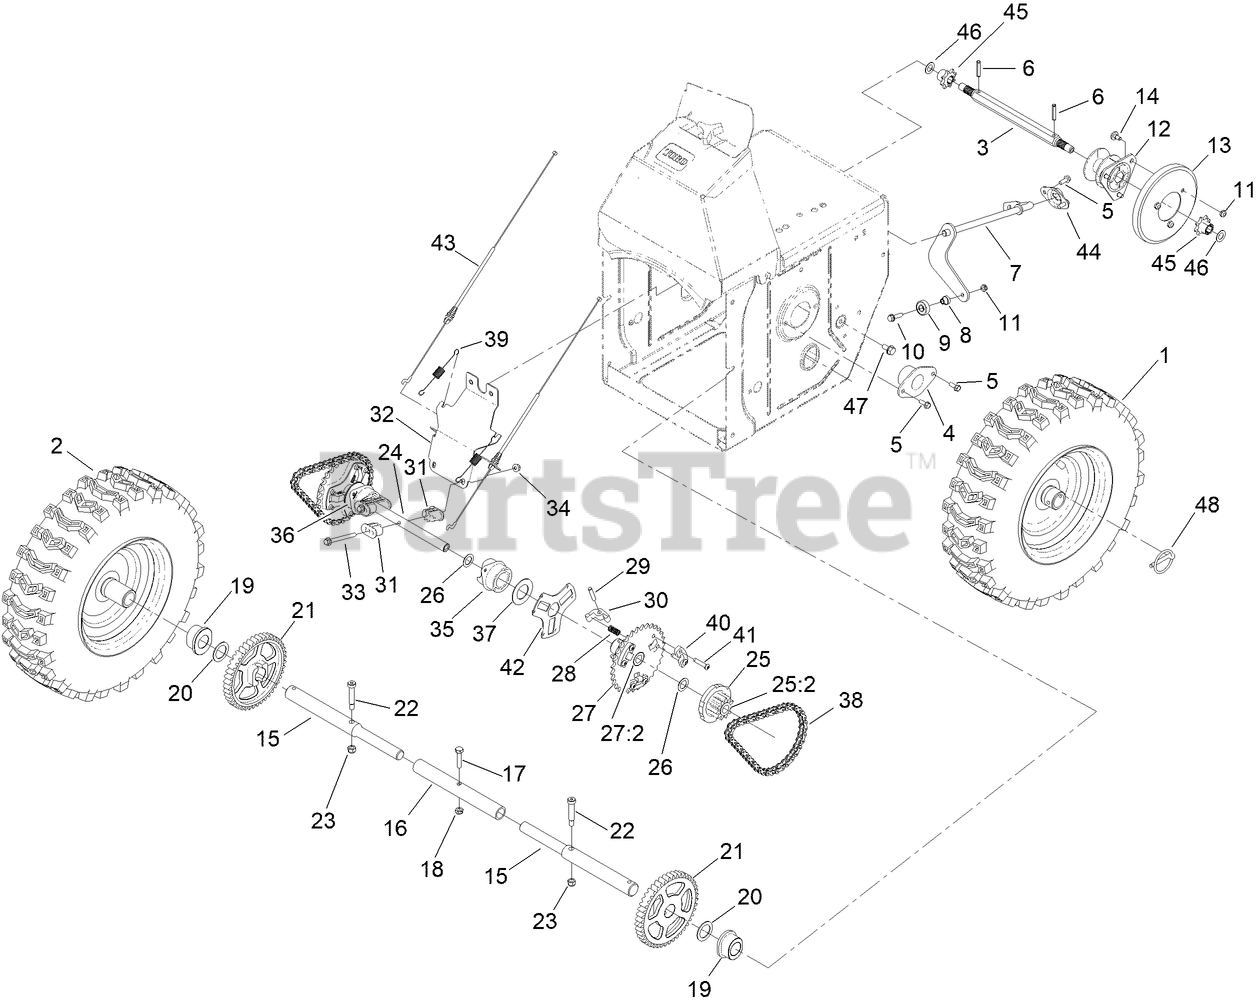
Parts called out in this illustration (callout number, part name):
1	LH WHEEL AND TIRE ASM
2	RH WHEEL AND TIRE ASM
3	SHAFT-HEX
4	RETAINER-BEARING
5	SCREW-HWH
6	PIN-ROLL, SLOTTED
7	SHIFT ROD
8	SPACER-PLATE, SHIFT
9	BEARING-BALL
10	SCREW-HWHTF
11	NUT-HEX
12	TRUNNION
13	WHEEL-FRICTION
14	SCREW-SHOULDER
16	TUBE-AXLE
17	SCREW-HH
18	NUT-HEX
19	BUSHING-AXLE
20	WASHER-THRUST
21	GEAR-AXLE
22	BOLT-SHOULDER, HSH
23	NUT-HEX
24	SHAFT-INTERMEDIATE
25	11T GEAR ASM
25:2	BUSHING-FLANGE
26	WASHER-FLAT
27	32T SPROCKET ASM
27:2	BUSHING-FLANGE
28	SPRING-COMPRESSION
29	PIN-DOWEL
30	PAWL-CLUTCH
31	GUIDE-COLLAR
32	BRACE-SHIFT, COLLAR
33	SCREW-HHF
34	NUT-FLANGE, NI
35	COLLAR-SHIFT, LH
36	COLLAR-SHIFT, RH
37	WASHER-THRUST
38	CHAIN-ROLLER
39	SPRING-EXTENSION
40	SUPPORT-PAWL
41	SCREW-BHCS
42	RETAINER-PAWL, PIN
43	CABLE-CLUTCH
44	RETAINER-ROD, SHIFT
45	GEAR-PINION, 8 TOOTH
46	WASHER-PLAIN
47	SCREW-HWHTF
48	PIN-KLIK
